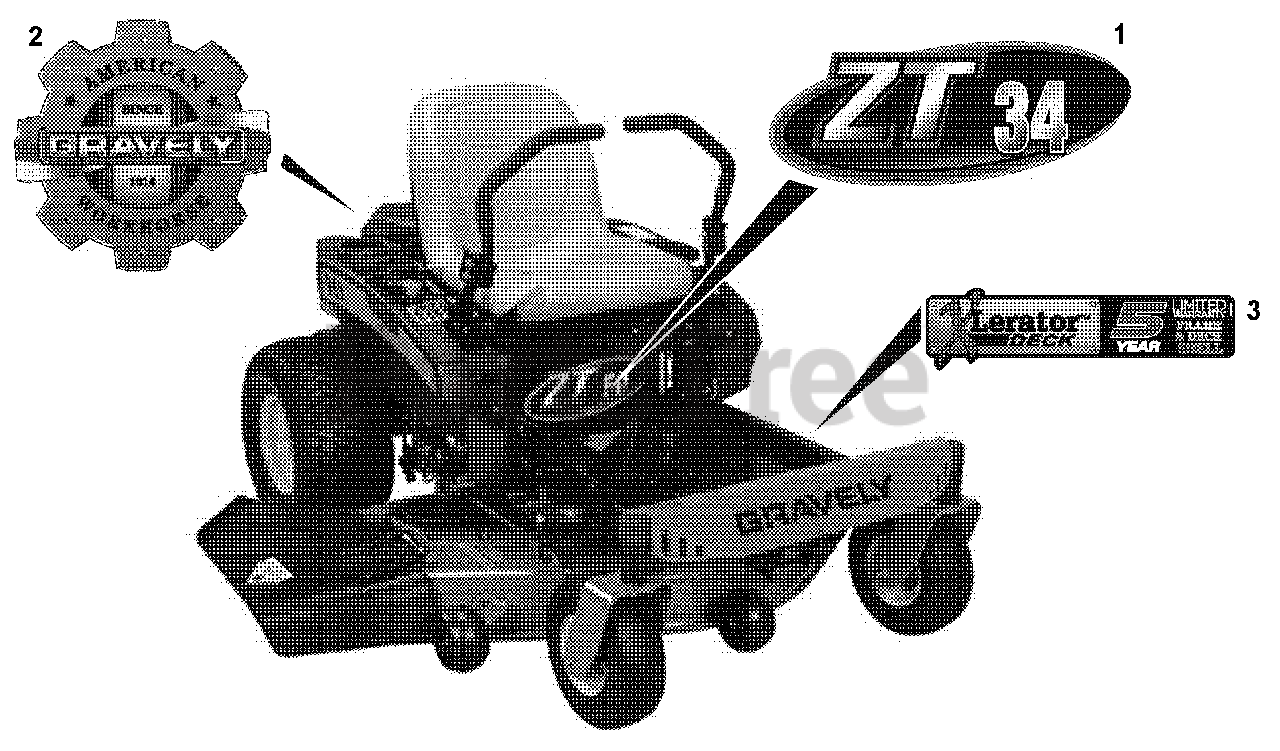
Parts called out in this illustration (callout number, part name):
1	Decal, ZT 34 (915146, 168)
2	Decal, Gravely Heritage, Small
3	Decal, Deck Warranty - Xcel
